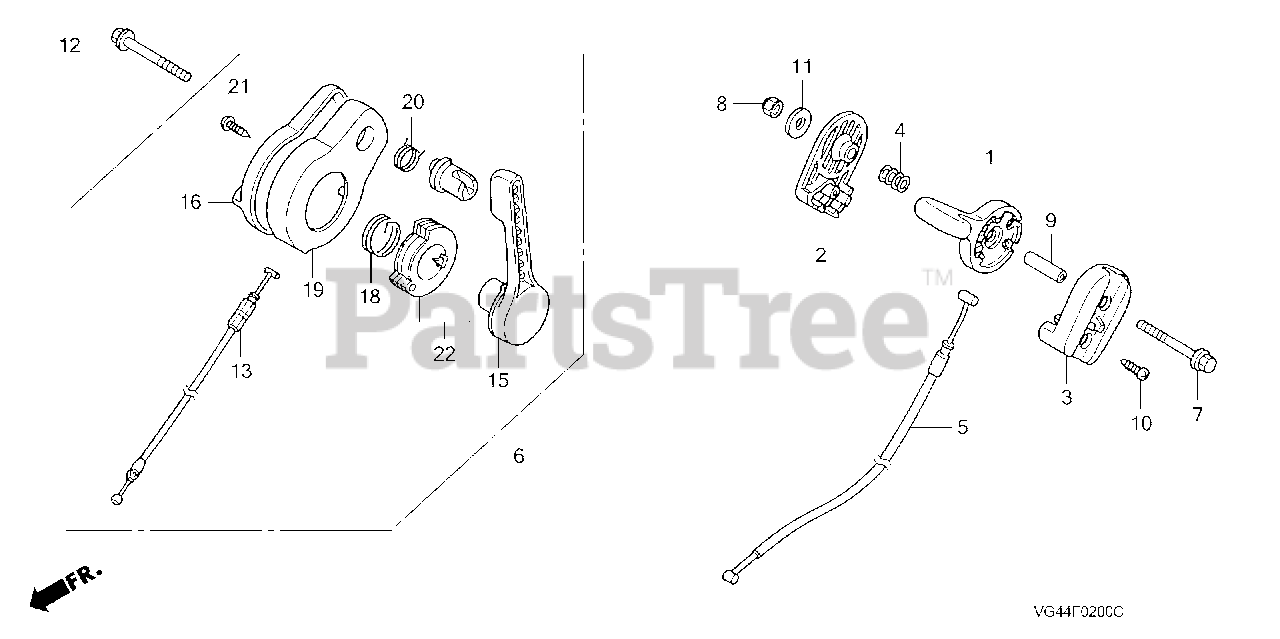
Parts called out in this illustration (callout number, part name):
1	LEVER, THROTTLE
2	CASE, R. THROTTLE LEVER
3	CASE, L. THROTTLE LEVER
4	SPRING, THROTTLE LEVER
5	CABLE, THROTTLE
6	CONTROL ASSY., ROTO-STOP
7	BOLT, FLANGE (6X65)
8	NUT, NYLON LOCK (6MM)
9	COLLAR, THROTTLE
10	SCREW, TAPPING (4X12)
11	WASHER, PLAIN (6MM)
12	BOLT, FLANGE (6X45)
13	CABLE, ROTO-STOP
15	LEVER, ROTO-STOP
16	CASE, ROTO-STOP (R)
18	SPRING, CONTROL LEVER
19	CASE, ROTO-STOP (L)
20	SPRING, BAIL
21	SCREW, TAPPING
22	CAM KIT, ROTO-STOP
